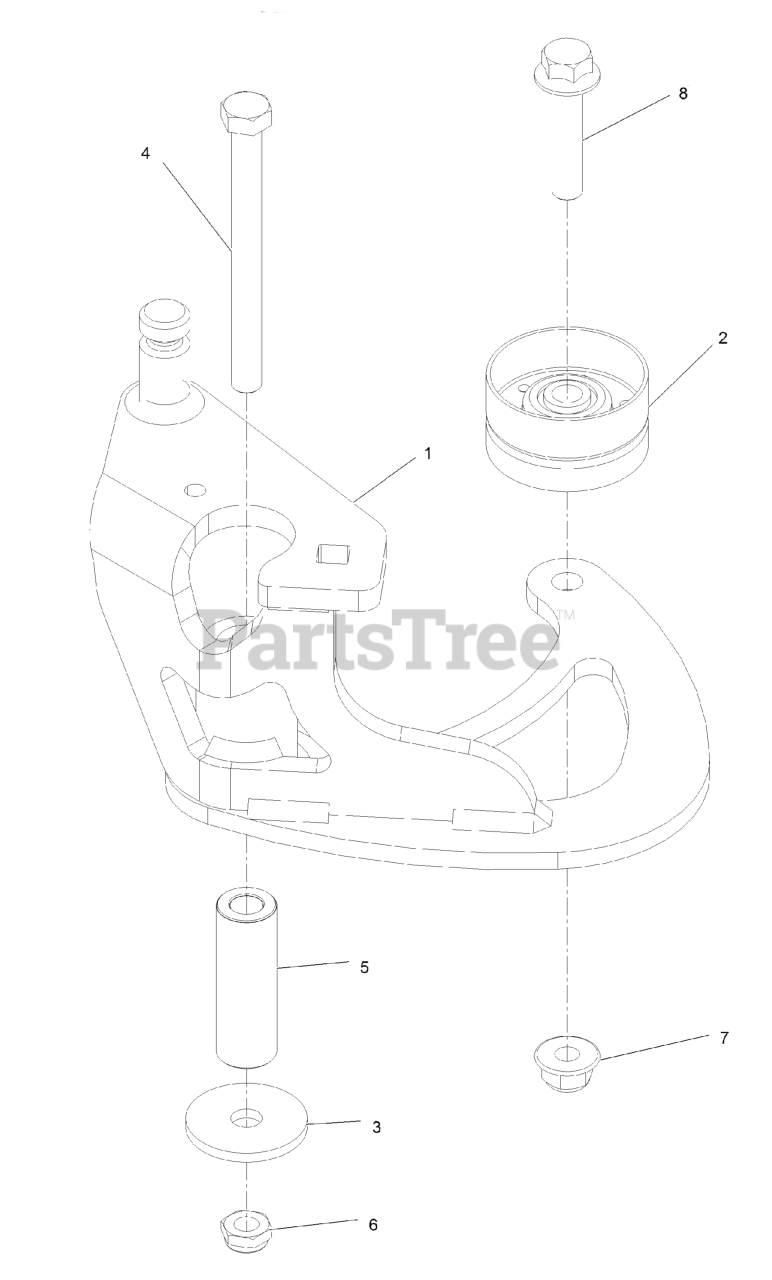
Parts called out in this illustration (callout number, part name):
1	ASM, IDLER ARM W/ BUSHINGS
2	IDLER, FLAT
4	SCREW-HH
5	TUBE, IDLER PIVOT
7	NUT-HF, NI
8	SCREW-HHF
